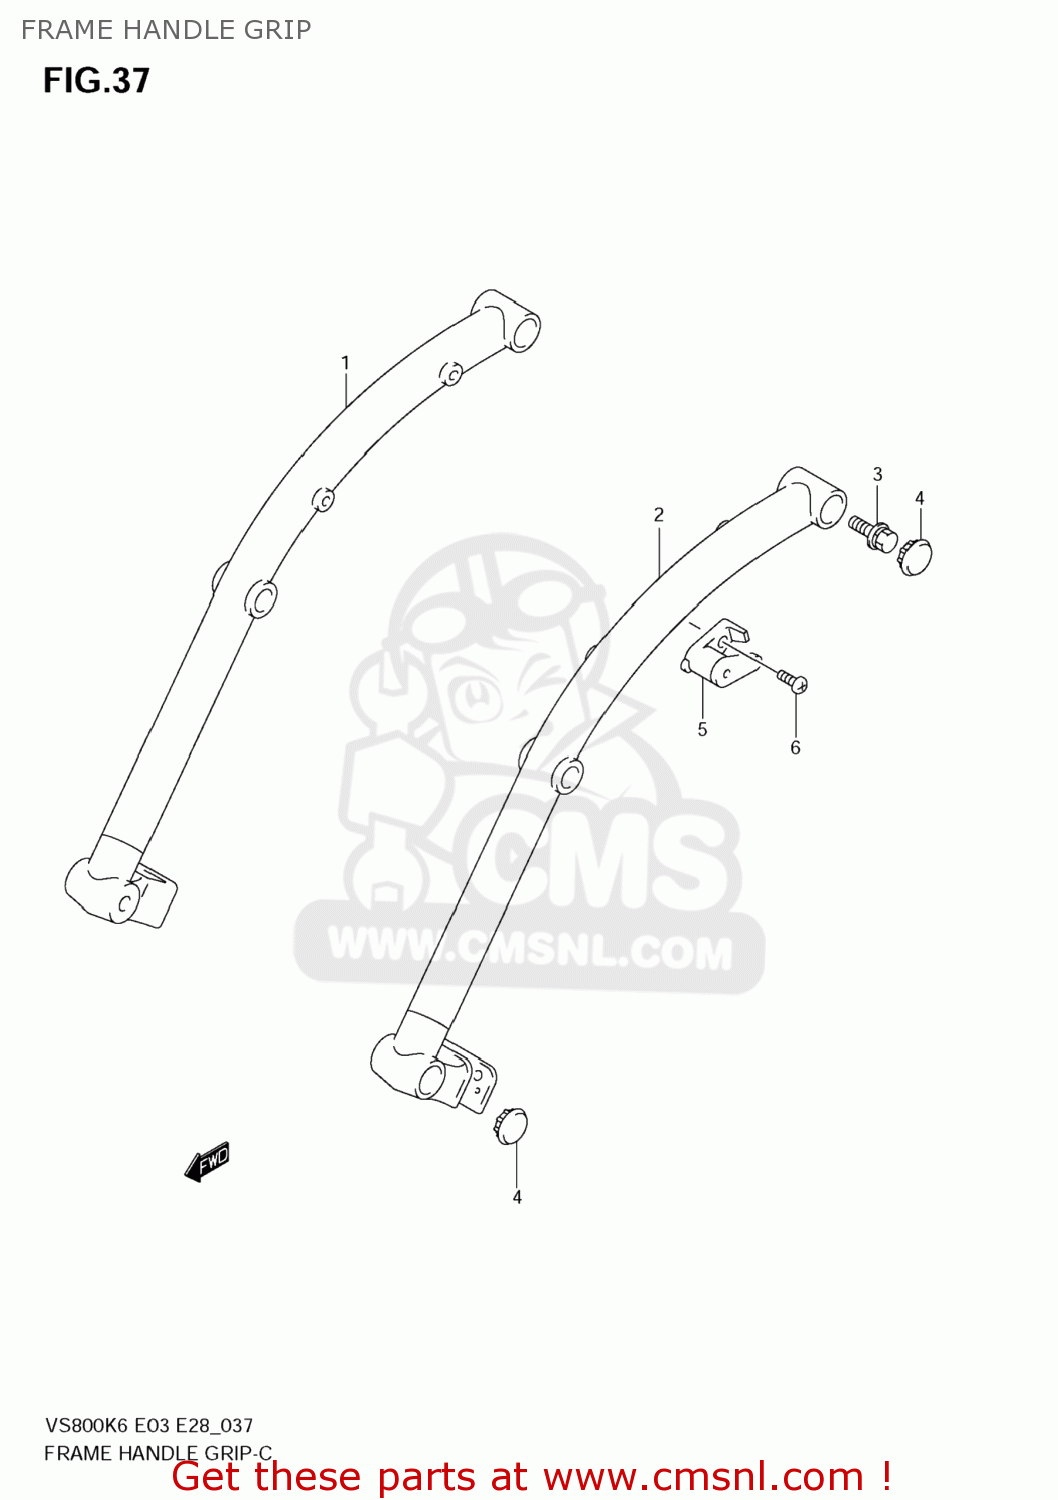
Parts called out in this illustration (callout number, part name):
1	GRIP,FRAME HANDLE RH
2	GRIP,FRAME HANDLE LH
3	BOLT
4	CAP,FRAME HANDLE GRIP
5	LOCK SET,HELMET
6	SCREW
